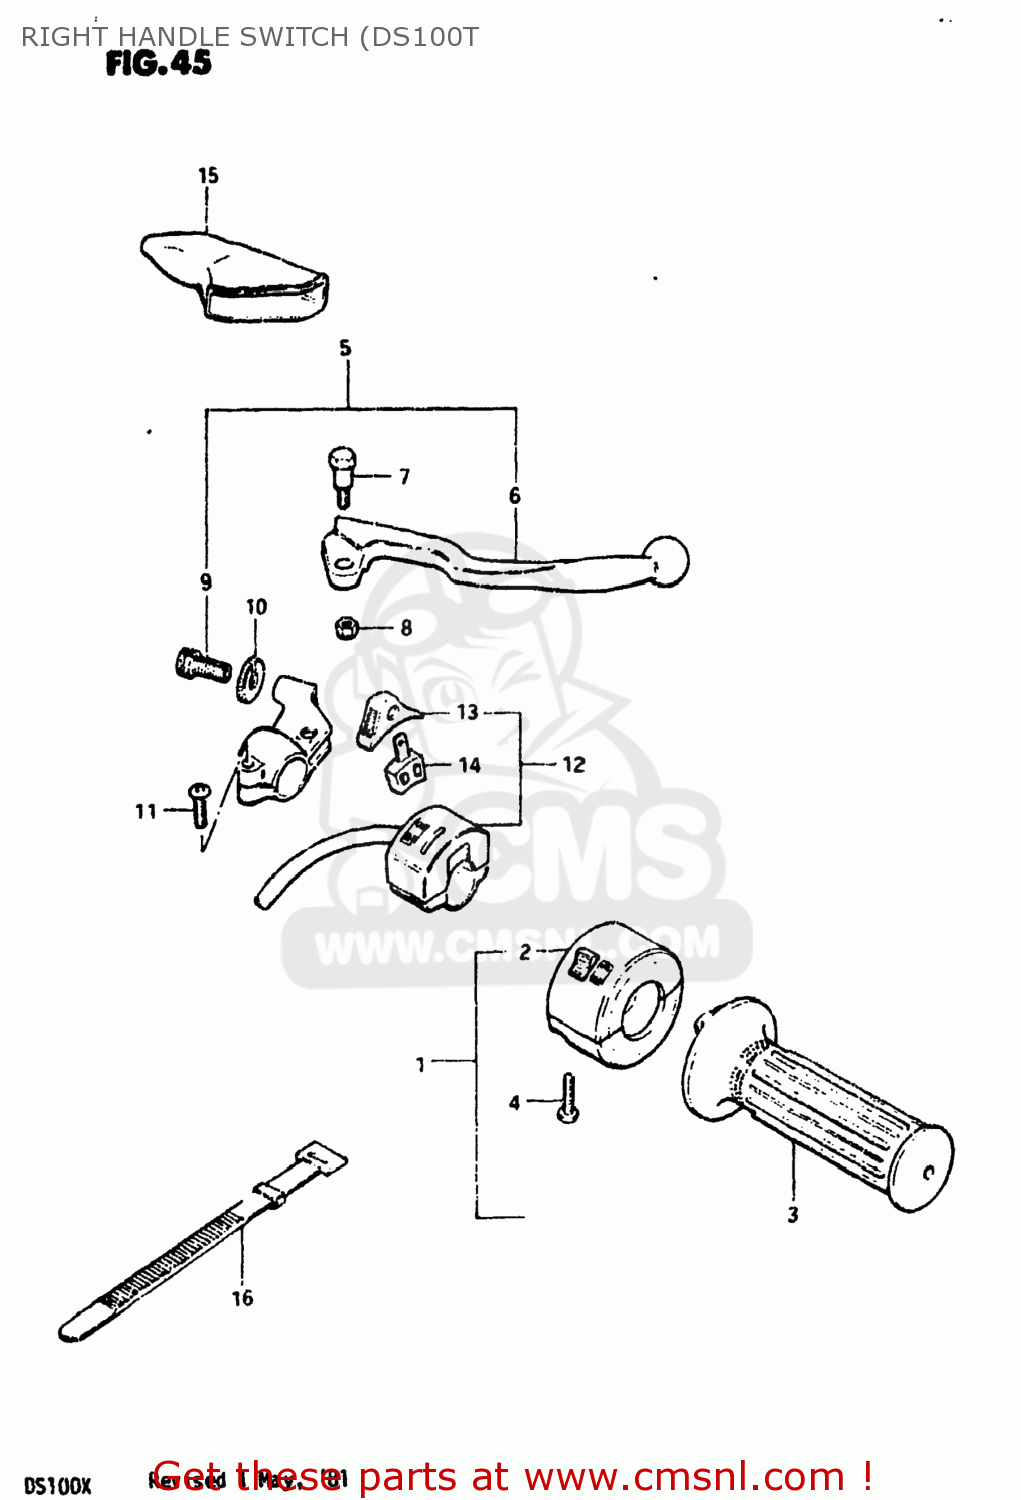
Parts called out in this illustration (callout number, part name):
1	CASE ASSEMBLY,THROTTLE
2	CASE ASSY,THROTTLE
3	GRIP,THROTTLE
4	SCREW
5	LEVER ASSEMBLY,BRAKE
6	LEVER,BRAKE
7	BOLT,LEVER
8	NUT 6MM
9	ADJUSTER,CABLE
10	NUT,CABLE ADJUSTER
11	SCREW
12	SWITCH ASSEMBLY,LIGHTING
13	KNOB,LIGHTING & DIMMER
14	BLOCK,LIGHTING/DIMMER
15	COVER,CLUTCH LEVER
16	CLAMP(L:120)
